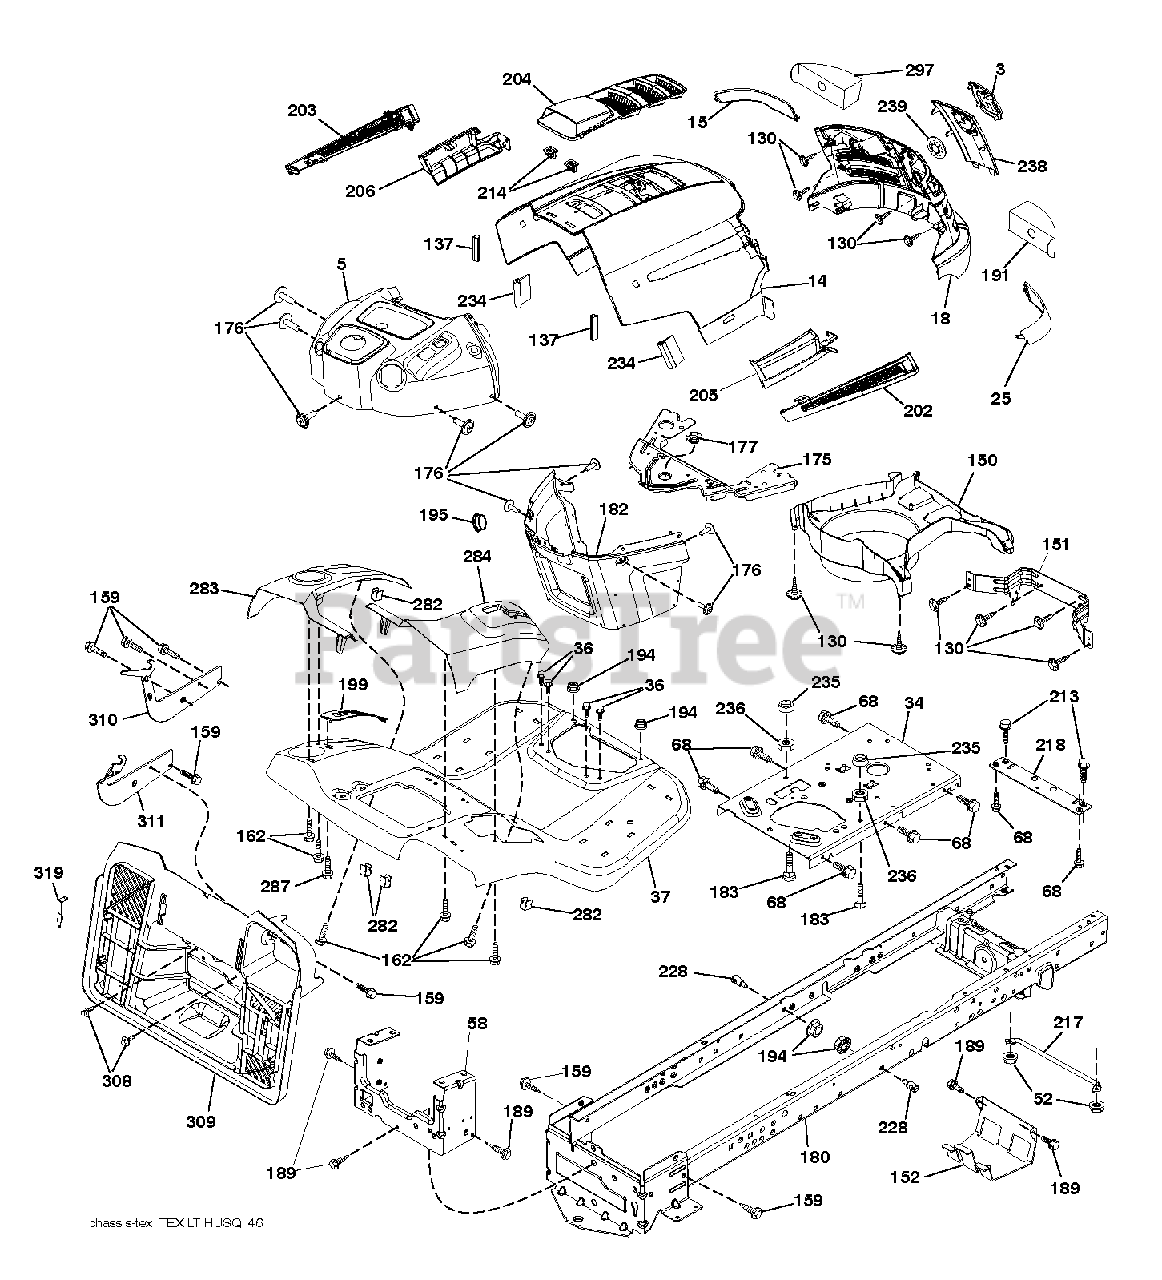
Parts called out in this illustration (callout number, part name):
3	RP LOGO
5	SUBASM.DASH.UPPER.W/BUMPER
14	HOOD.HUSQVARNA.LT.ORANGE
15	LENS.HUSQVARNA LT.RH
18	GRILLE.SVC.HUSQVARNA.GREY
25	LENS.HUSQVARNA LT.RH
34	PLATE.ENGINE.WELDED.CHASSIS
36	SCREW 5/16"
37	FENDER.TEX.SRD.CRD.BASE
52	LOCKNUT
58	DRAWBAR UPPER 2PC SMALL FENDER
68	SCREW LT
130	SCREW.#10 X 0.750.BOS
137	BUMPER DASH
151	BRACKET PIVOT
152	SHIELD.BROWNING.W/TEX
159	SCREW, 3/8-16X3/4
162	SCREW.HI-LO.CONSOLE
175	CROSSMEMBER
176	SCREW.#10-24X5/8.RN.QU
177	BUSHING STEERING
180	CHASSIS.WLDMNT.14GA.2PC.18".TI
182	DASH.LOWER.PREDATOR LT
183	BOLT.5/16-18X1-1/4 FULL THD
189	SCREW
191	INSERT.REFLECTIVE.RH.
194	NUT LOCK HEX FLANGE 5/16-18
195	PLUG.TEX.DASH.SVC.MINDER.GREY
199	PLATE DECK LIFT
202	VENT.SIDE.HUSQVARNA.LT.RT
203	VENT.SIDE.HUSQVARNA.LT.LFT
204	SUBASM.TOP.VENT.HUSQ.LT
205	SKIRT.SIDE.HUSQVARNA.LT.RT
206	SKIRT.SIDE.HUSQVARNA.LT.LEFT
213	BOLT
214	CLIP.RETAINER.TINNER.
217	ROD.PIVOT.HOOD
218	X-PIECE.HOOD.STOP.NON/
228	STUD.FASTNER.W/ANTI-ROTATE
234	BUMPER.HOOD.TEX.HUSQVARNA
235	SPACER FENDER
236	NUT.CENTERLOCK.5/16-
238	TRIM.HUSQ LT.668
282	CLIP.RETAINER.CONSOLE.LT.HUSQ
283	CONSL.DECKLIFT.LH.SRD.TEX.CRD
284	CONSL.SHIFT.GEAR.RH.SRD.GREY
287	SCREW 1/4X20
297	INSERT REFLECTIVE
308	BOLT, 5/16-18 X 1 3/4
309	BACKPLATE.BAGGER.V2.SRD
319	BRACKET.ACTUATOR.BAGGER.SRD
